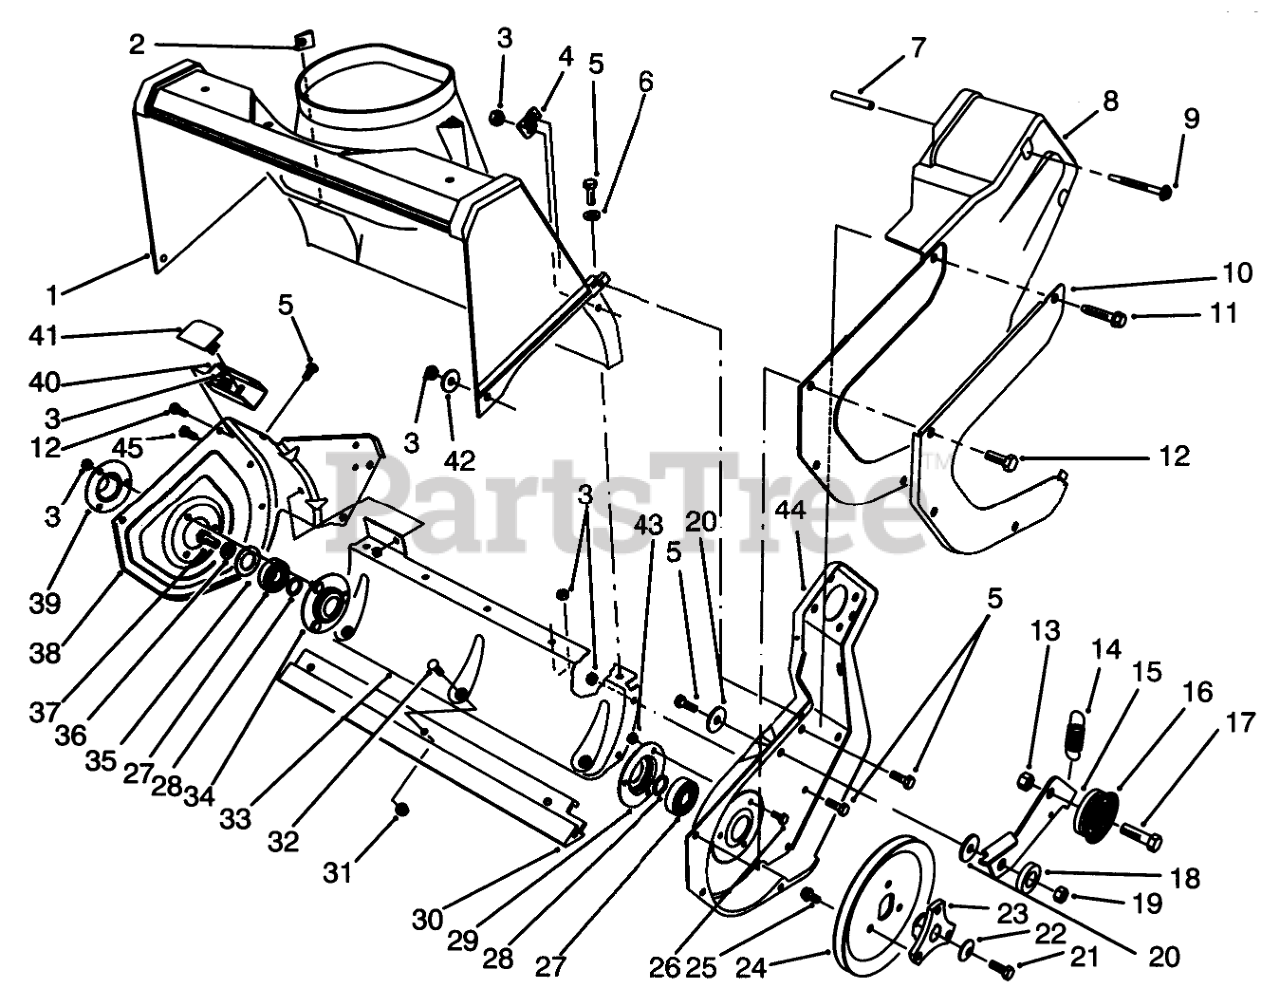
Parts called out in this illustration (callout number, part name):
1	HOUSING
2	SPEED NUT
3	NUT-LOCK, NI
4	BRACKET-HOUSING
5	SCREW-HH
6	WASHER-FLAT
7	TUBULAR SPACER
8	DRIVE COVER
9	SCREW-HWHTF
10	Guard-Drive Cover
11	SCREW-HWH, TAP
12	SCREW-HWH
13	NUT-LOCK, NI
14	SPRING-BRAKE
15	BRAKE ARM IDLER
16	PULLEY-IDLER
17	SCREW-HH
18	SPACER
19	NUT-LOCK, NI
20	WASHER-FLAT
21	SCREW-HH
22	WASHER-BELLEVILLE
23	HUB-MOUNTING, PULLEY
24	ROTOR PULLEY
25	SCREW
26	SCREW-SHH
27	BEARING-BALL
28	WASHER-THRUST
29	FLANGE-BEARING
30	SCRAPER
31	NUT-LOCK, HHF
32	SCREW-CARR
33	Housing-Lower
34	FLANGE-BEARING
35	WASHER-RUBBER
36	WASHER-FLAT
37	SCREW-HHF
38	Sideplate-R.H.
39	Trough
40	SIDEPLATE BRKT SUPT
41	BRACKET COVER
42	WASHER-FLAT
43	NUT-LOCK, NI
44	Sideplate L.H.
45	SCREW-HH
